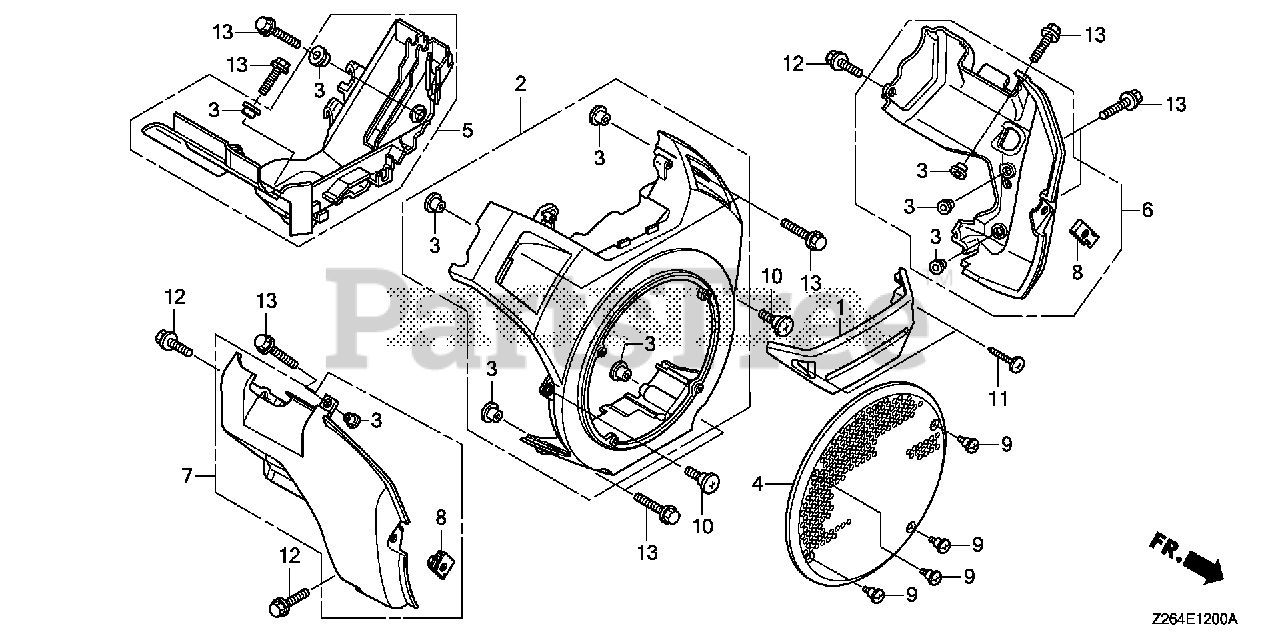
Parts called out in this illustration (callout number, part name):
1	COVER, FUEL PUMP
2	COVER, FAN *NH1* (BLACK)
3	COLLAR, FAN COVER
4	PROTECTOR, FAN COVER
5	SHROUD (UPPER)
6	SHROUD, R. (LOWER)
7	SHROUD, L. (LOWER)
8	NUT, FENDER SETTING
9	SCREW, SPECIAL (4X10)
10	SCREW, SPECIAL (6X15)
11	SCREW, TAPPING (5X20)
12	BOLT, FLANGE (6X16)
13	BOLT, FLANGE (6X20)
